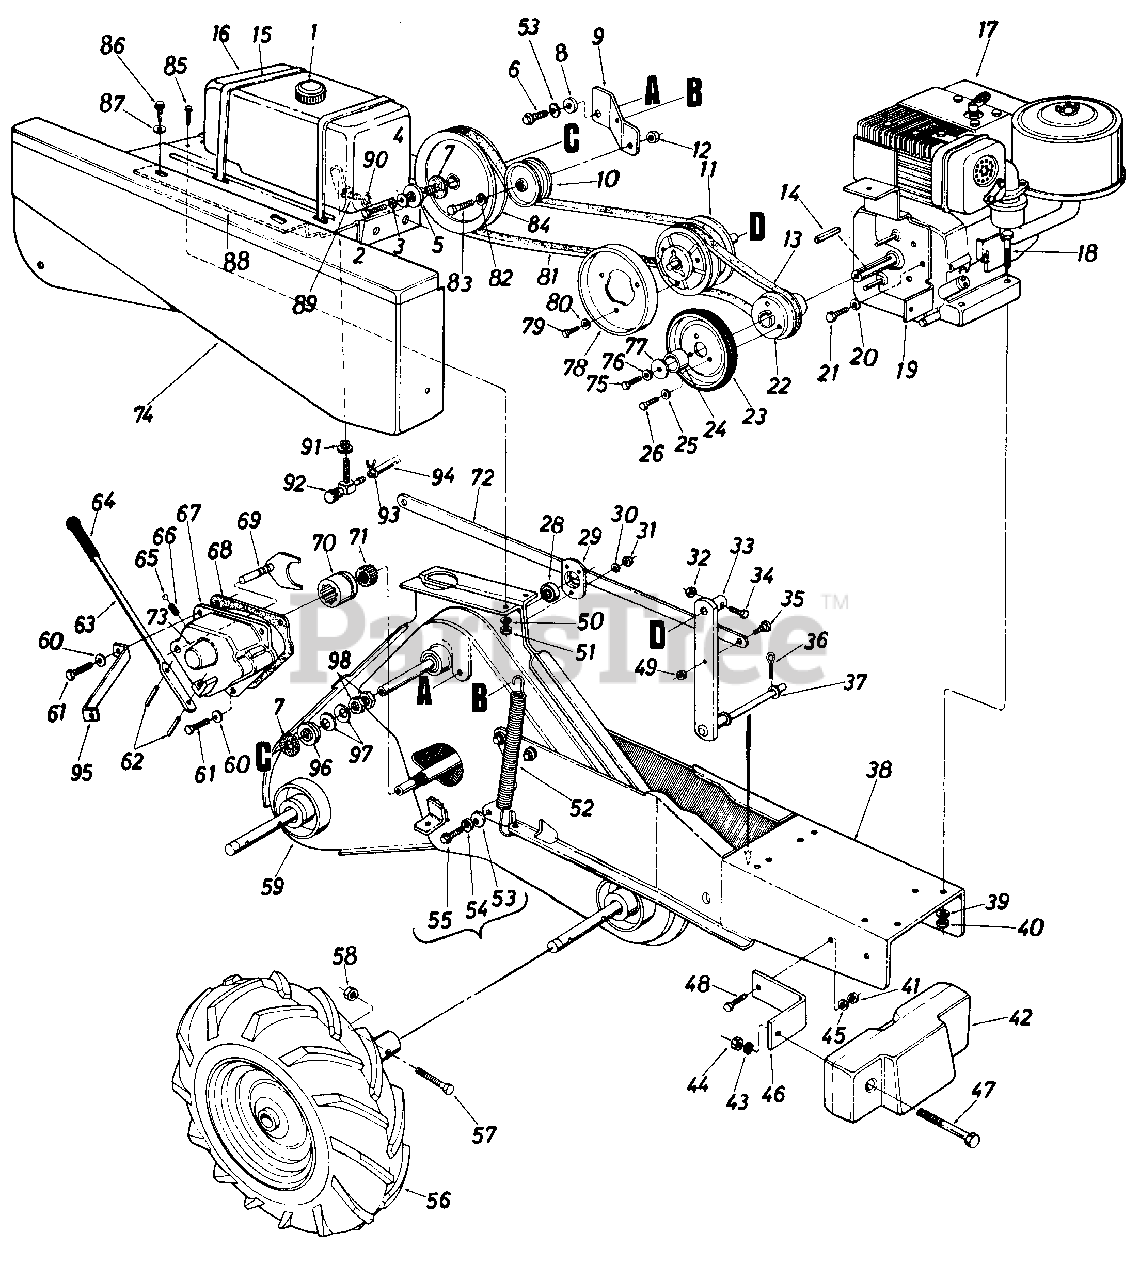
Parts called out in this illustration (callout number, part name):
1	Gas Cap
2	Hex L-Bolt 5/16-24 x 1.5" Lg.
3	L-Wash. 5/16" I.D.
4	Fl-Wash. 5/16" I.D. x 1.125" O.D.
5	Friction Disc Ass'y.
6	Hex Bolt 3/8-24 x 1.25" Lg.
7	Friction Pad
8	Shoulder Spacer
9	Idler Bracket
10	Fl-Idler 2.75" Dia.
11	Variable Speed Ass'y.
12	Hex Ins. L-Nut 3/8-16 Thd.
13	"V"-Belt 5/8" x 27.0" Lg.
14	Sq. Key 1/4" x 1.50" Lg.
15	Cable Tie
16	Gas Tank
17	Engine
18	Hex Bolt 5/16-18 x 1.75" Lg.
19	Belt Cover Support Ass'y.
20	Internal L-Wash. 1/2" I.D.
21	Hex Bolt 1/2-20 x .75" Lg.
22	Engine Pulley Ass'y.
23	Friction Wheel Ass'y.
24	Spacer
25	L-Wash. 5/16" I.D.*
26	Hex Bolt 5/16-18 x .50" Lg.
28	Ball Bearing
29	Bearing Housing 1-3/8" O.D.
30	L-Wash. 1/4" I.D.
31	Hex Nut 1/4-28 Thd.
32	Hex Ins. L-Nut 1/4-20 Thd.
33	Variable Speed Brkt. Ass'y.
34	Hex Bolt 1/4-20 x 1.25" Lg.
35	Shld. Bolt 1/2" Dia. x .25" Lg.
36	Cotter Pin 1/8" Dia. x 1.0" Lg.*
37	Fl-Wash. .686" I.D. x 1.25" O.D.
38	Frame Ass'y.
39	L-Wash. 5/16" I.D.
40	Hex Nut 5/16-18 Thd.
41	Hex Cent. L-Nut 3/8-24 Thd.
42	Weight
43	Fl-Wash. .50" I.D. x 1.0" O.D
44	Hex Nut 1/2-13 Thd.
45	L-Wash. 3/8" I.D.
46	Weight Mtg. Brkt.
47	Hex Bolt 1/2-13 x 4.50" Lg.
48	Hex Bolt 3/8-24 x 1.00" Lg.
49	Hex Ins. L-Nut 3/8-16 Thd.
50	L-Wash. 1/4" I.D.
51	Hex Cent. L-Nut 1/4-28 Thd.
52	Spring Idler Bracket
53	Belleville Wash. 3/8" I.D.
54	L-Wash. 3/8" I.D.*
55	Hex Self-Tap Scr. 3/8-16 x .75" Lg.
56	Wheel Ass'y. Comp.-R.H.
57	Hex Bolt 3/8-24 x 1.25n Lg.*
58	Hex Ins. L-Nut 3/8-24 Thd.
59	Chain Case Ass'y. Comp.
60	L-Wash. 5/16 I.D.*
61	Hex Tap Tite Scr. 5/16-18 x .75" Lg.
62	Headed Spiral Pin 3/16 x 13/16" Lg.
63	Engagement Lever
65	Ball Detent .250" Dia.
66	Compression Spring
67	Shift Housing-R.H.
68	Gasket-Shift Housing
69	Shift Yoke Ass'y.-R . H .
70	Clutch Dog
71	Clutch Dog Driver
72	Control Brkt.
73	Bearing
74	Shroud Belt Cover
75	Hex Bolt 7/16-20 x 1.00" Lg.
76	L-Wash. 7/16" I.D.
77	Fl-Wash. .44 I.D. x 1.38 O.D
78	Friction Disc
79	Hex Bolt 1/4-28 x .Son Lg.
80	L-Wash. 1/4" I.D.*
81	"V"-Belt 5/8" x 51' Lg.
82	L-Wash. 3/8" I.D.*
83	Hex Bolt 3/8" x 1.50" Lg.*
84	Input Pulley-Chain Case
85	Hex Bolt 1/4-28 x .62" Lg.
86	Hex Wash. Hd. Self-Tap Scr.
87	Fl-Wash. 1/4" I.D.
88	Tank Mounting Brkt.
89	Hex Bolt 5/16-18 x .75'1 Lg.*
90	L-Wash. 5/16" I.D.*
91	Bushing-Gas Line
92	Shut-Off Valve
93	Clamp Gas Line
94	Gas Line 14-1/2" Lg.
95	Brace
96	Floating Disc
97	Spring Bell-Wash.
98	Hex Jam Nut 1.0-14
